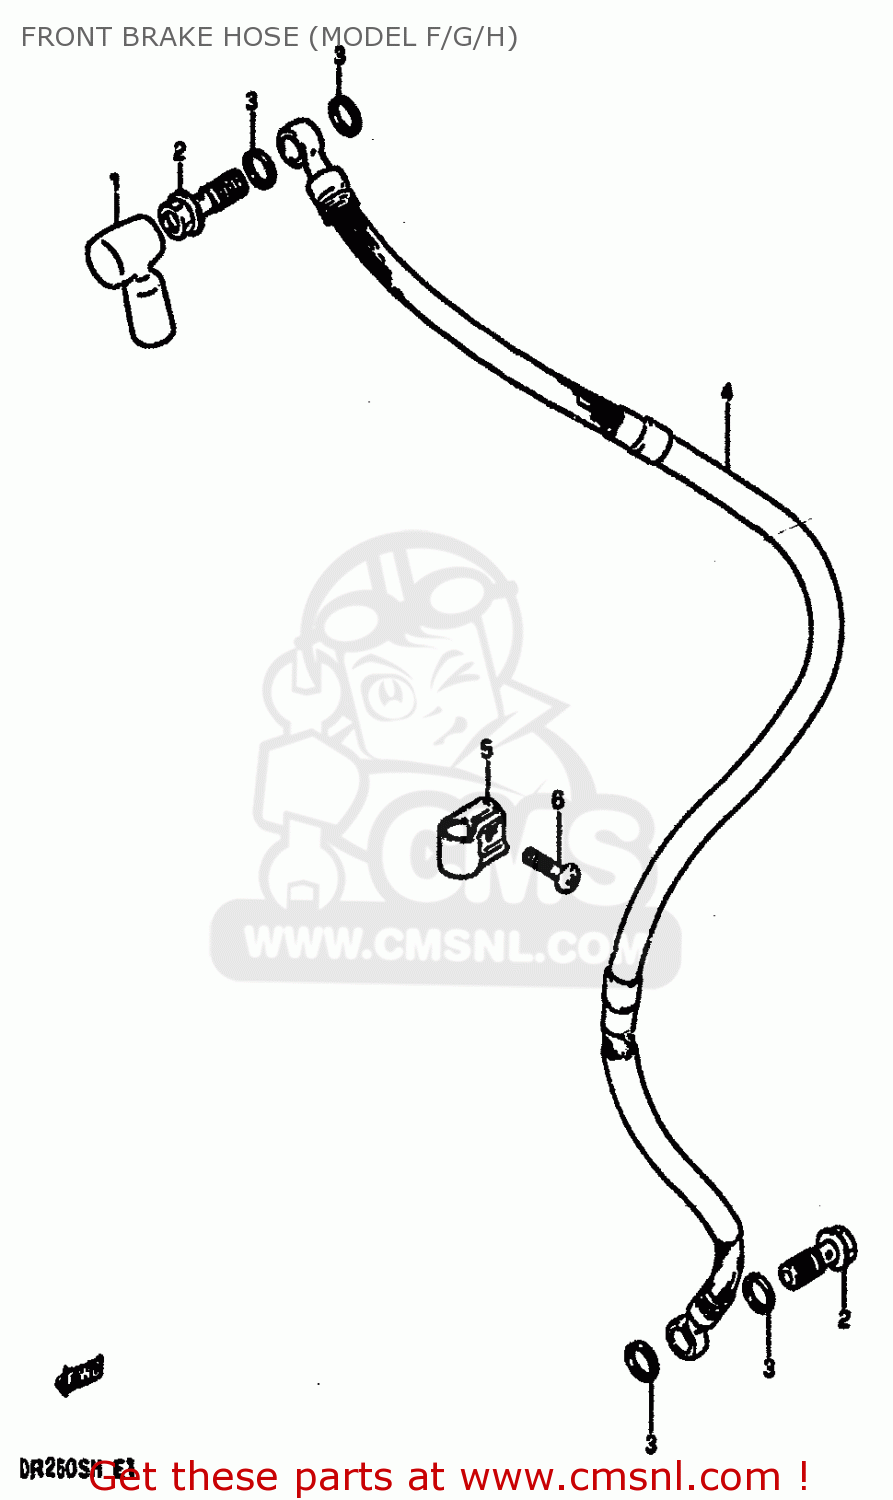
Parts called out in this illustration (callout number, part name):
1	BOOT,MASTER CYLINDER
2	BOLT UNION
3	WASHER(10X15X1.5)
4	HOSE BRAKE
5	CLAMP,BRAKE HOSE
6	SCREW
